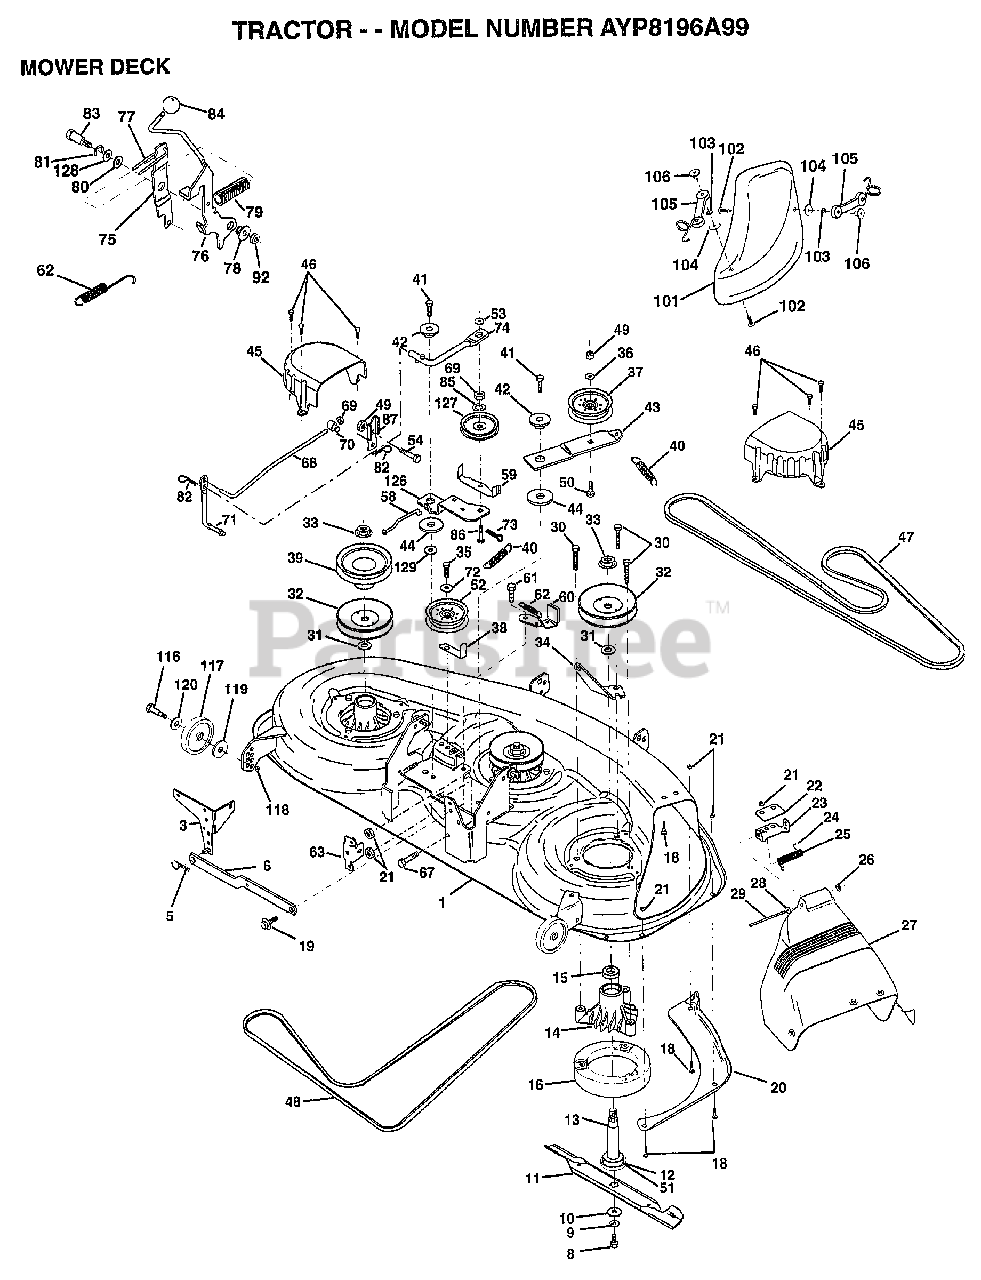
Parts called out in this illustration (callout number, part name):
1	"DECK.ASM.MOWER46"""
3	BRKT.ASM.SW.44/50
8	BLADE BOLT
10	WASHER.HARD.BLADE
11	"BLADE MULCH 46"""
12	BEARING.BALL
13	SHAFT.ASM.W/BRNG
14	HOUSING.MAND.44.V
15	BEARING
16	STRIPPER RND MWR
18	BOLT
19	BOLT SHD 5/16-18
20	BAFFFLE.VORTEX.46
22	STIFFENER BRKT
23	DEFLECTOR BRKT
24	CAP-SLEEVE LT
26	NUT PUSH M
27	SHIELD DEFLECTOR
28	WASHER
29	HINGE ROD
30	"SCREW-THD ROLL,WA"
31	WASHER
32	PULLEY.MAND.36/46
34	ANCHOR.SPRING.46
35	SCREW LT
36	WASHER
37	FLAT IDLER PULLEY
38	"KEEPER BELT,IDLER"
39	PULLEY.DRV.DCK.46
40	"SPRING.SEC.44""VEN"
41	SCREW
42	SPACER RETAINER
43	ARM.IDLER.DECK.46
44	HARDENED WASHER
45	COVER.MANDREL.46
46	SCREW.1/4-20X5/8
47	BELT-V.SEC.46.KEL
48	V BELT MOWER
50	BOLT.3/8-16X1.50
51	WASHER.FELT.
52	"PULLEY IDLER,FLAT"
53	WASHER
58	"LINK BRAKE, 43"""
59	"GUIDE BELT,46""MOW"
60	ARM ASM BRAKE
61	BOLT.SHOULDER.5/16-18
62	RETURN SPRING
63	"BRKT ROD,CLUTCH"
67	BOLT
69	NUT
70	TRUNION ADJ
71	PIVOT ROD
72	WASHER
73	COTTER PIN
74	LINK CLUTCH
75	ARM EXTENSION
76	LEVER.ASM.CLUTCH
77	SPRING KEEPER
78	BUSHING
79	SPRING.CLUTCH.MWR
80	WASHER
81	RING
82	RETAINER M
83	SHOULDER BOLT
84	KNOB.RD.7/16-14
85	LOCKWASHER
86	"BOLT CARR, SH"
87	BRACKET.EXTENSION
88	BOLT
92	NUT
101	COVER.MULCHING.
102	SCREW
103	LOCKWASHER
104	WASHER #10
105	LATCH ASSY.BAGGER
106	WELDNUT
116	BOLT M
117	WHEEL.GAGE.BLK.PL
118	LOCKNUT
119	WASHER
120	WASHER
127	PULLEY.IDLER.4.25
128	WASHER .T
129	WASHER T
